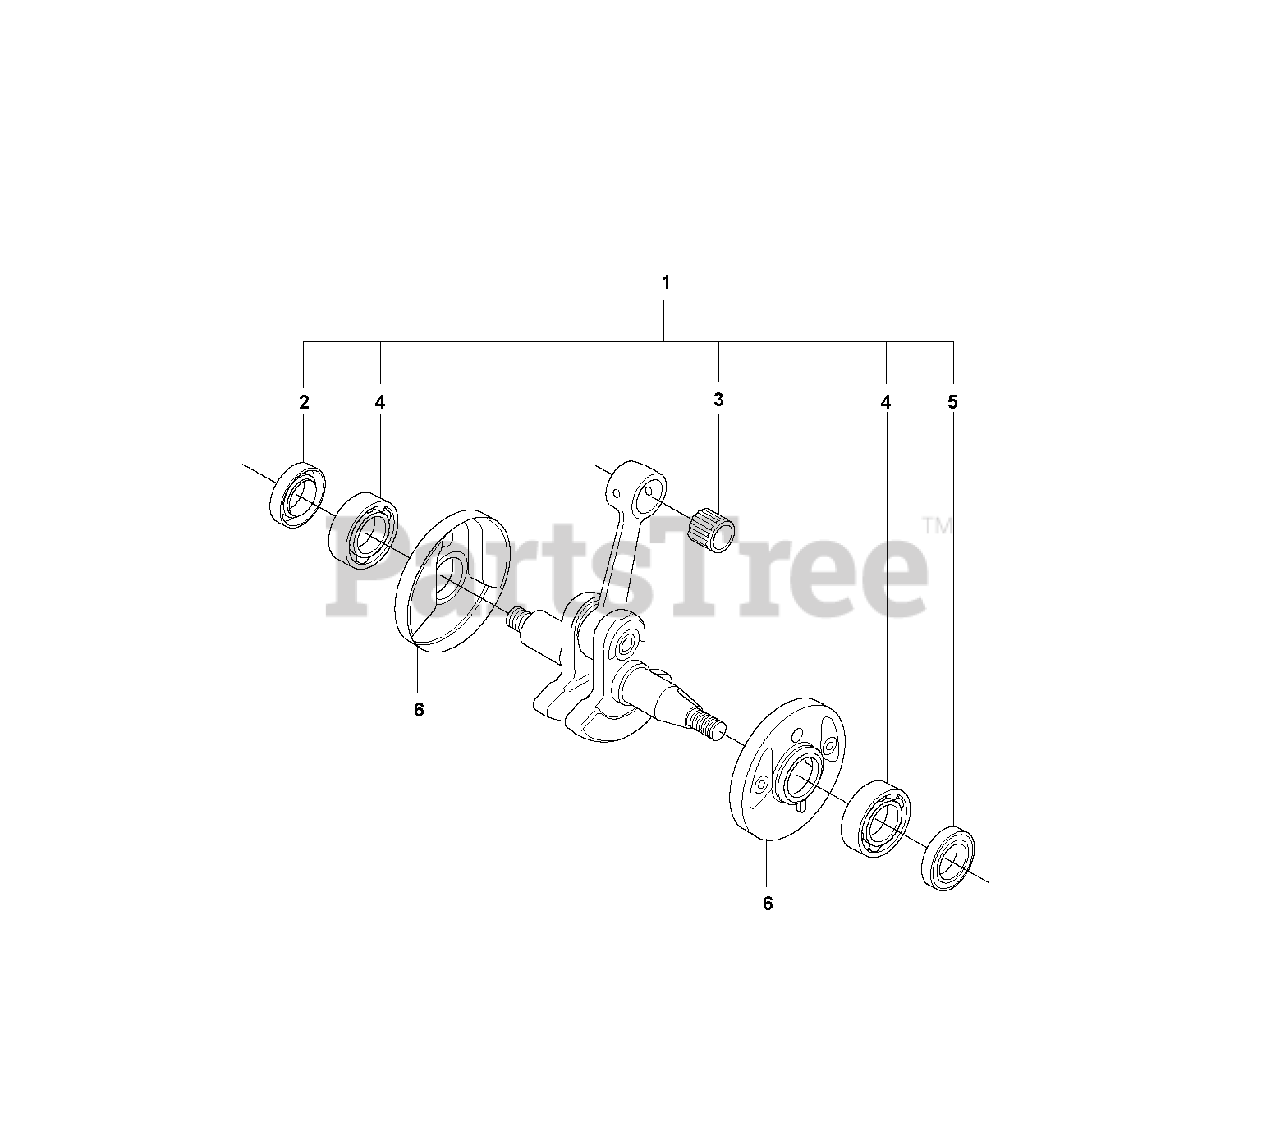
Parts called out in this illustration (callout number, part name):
1	CRANKSHAFT
2	SEALING RING
3	RP SUPPORT BUSHING
4	BALL BEARING-6202-C3 SKF
5	SEAL RING
